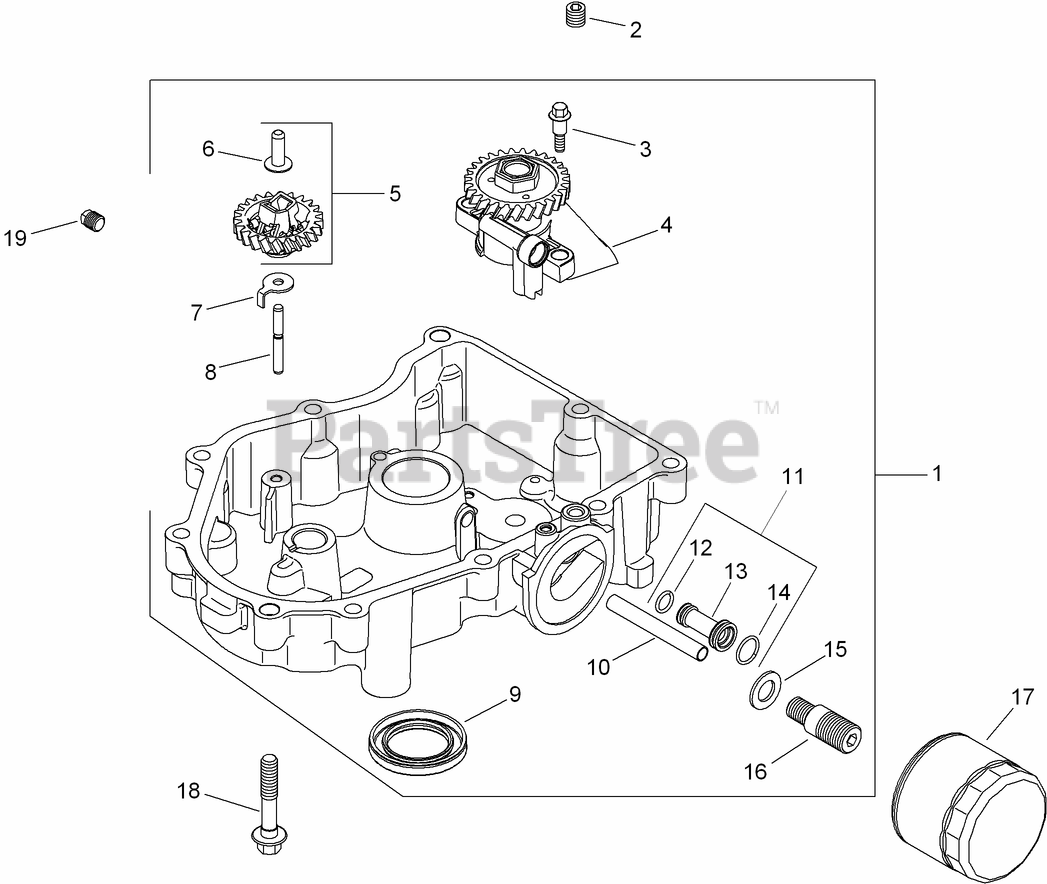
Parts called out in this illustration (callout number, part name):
1	OIL PAN ASM (INCLUDES 2-9, 11 [QTY 1], 24-27)
2	PLUG-PIPE, COUNTERSUNK (1/8)
3	SCREW-SHOULDER, THD FRM (M6x1.0x26.5)
4	OIL PUMP ASM
5	GOVERNOR GEAR KIT W/PIN (INCLUDES 5)
6	PIN-REGULATING, GOVERNOR
7	TAB-LOCKING
8	SHAFT-GEAR, GOVERNOR
9	SEAL-OIL
10	TUBE-FEED, OIL (FILTER TO PAN)
11	OIL FEED TUBE ASM (INCLUDES REF 10, 15, 16)
12	O-RING
13	TUBE-FEED, OIL
14	O-RING
15	WASHER-FLAT
16	NIPPLE-FILTER, OIL
18	SCREW-FLANGE (M8X1.25X45)
19	PLUG-PIPE, SQ HD (3/8)
